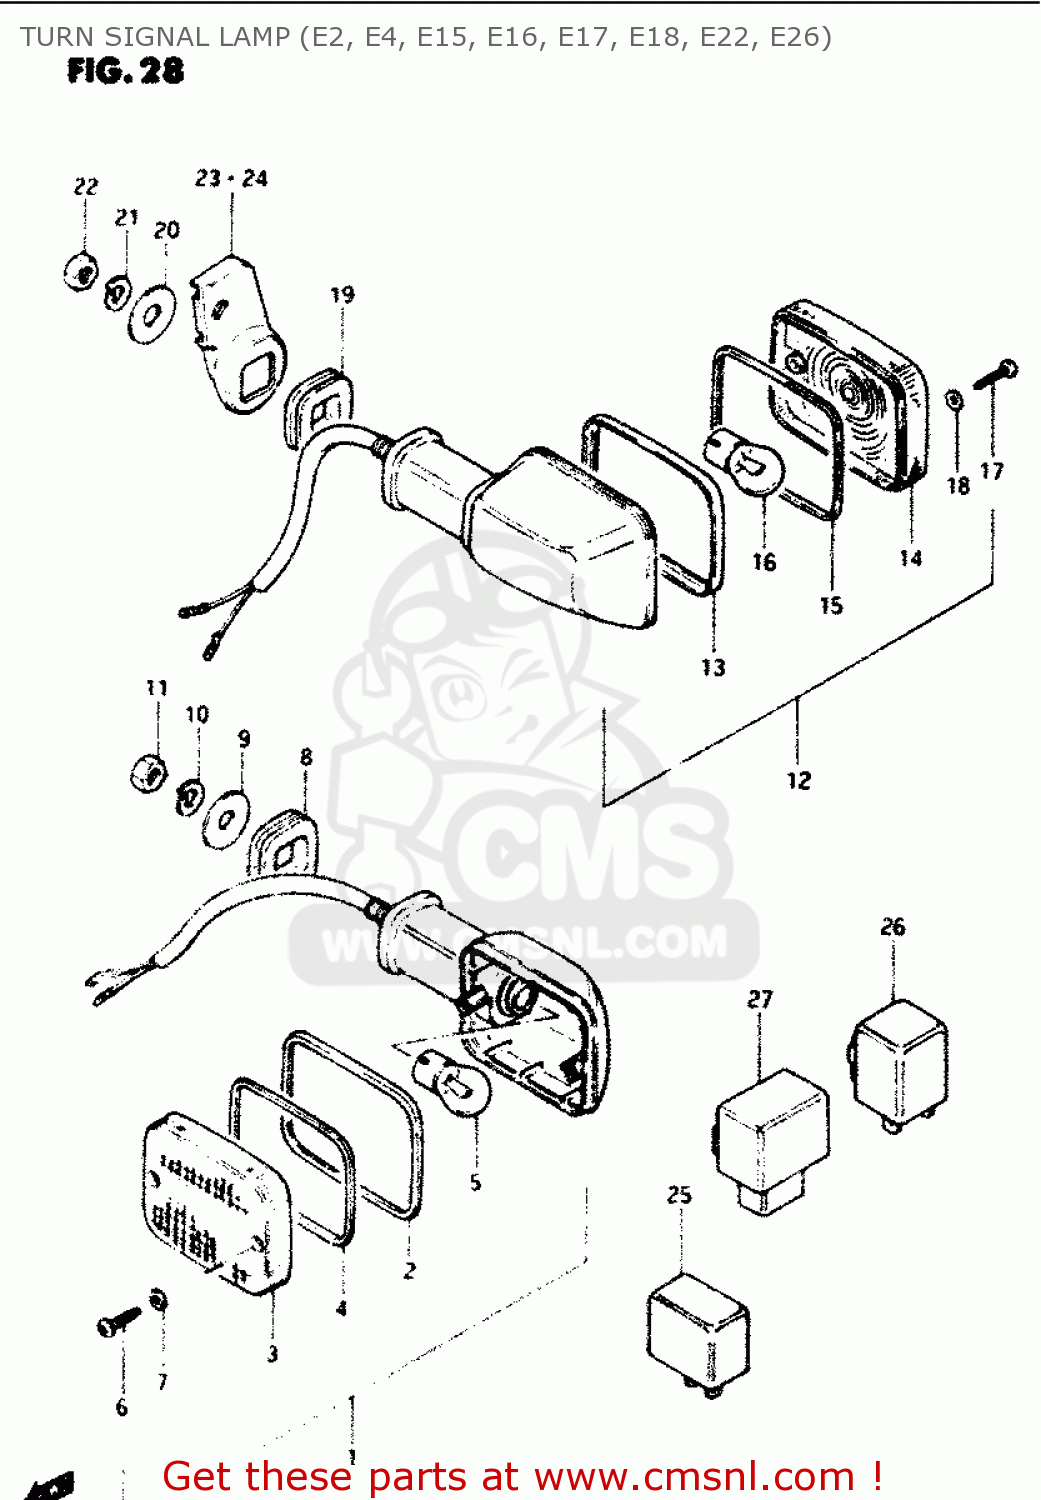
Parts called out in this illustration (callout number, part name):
1	LAMP ASSY, FRONT TURN SIGNAL
2	RIM
3	LENS
4	GASKET (NAS)
5	BULB(12V21W)
6	SCREW
7	GASKET (NAS)
8	CUSHION
9	WASHER (10.5X30X2.3)
10	LOCK WASHER
11	NUT
12	LAMP ASSY, REAR TURN SIGNAL
13	RIM
14	LENS
15	GASKET (NAS)
16	BULB(12V21W)
17	SCREW
18	GASKET (NAS)
19	CUSHION
20	WASHER (10.5X30X2.3)
21	LOCK WASHER
22	NUT
23	BRACKET,REAR TURN SIGNAL
24	BRACKET,REAR TURN SIGNAL
25	RELAY ASSY,TURNSIGNAL
26	RELAY ASSY,TUR
27	UNIT,TURN SIGNAL CONTROL
